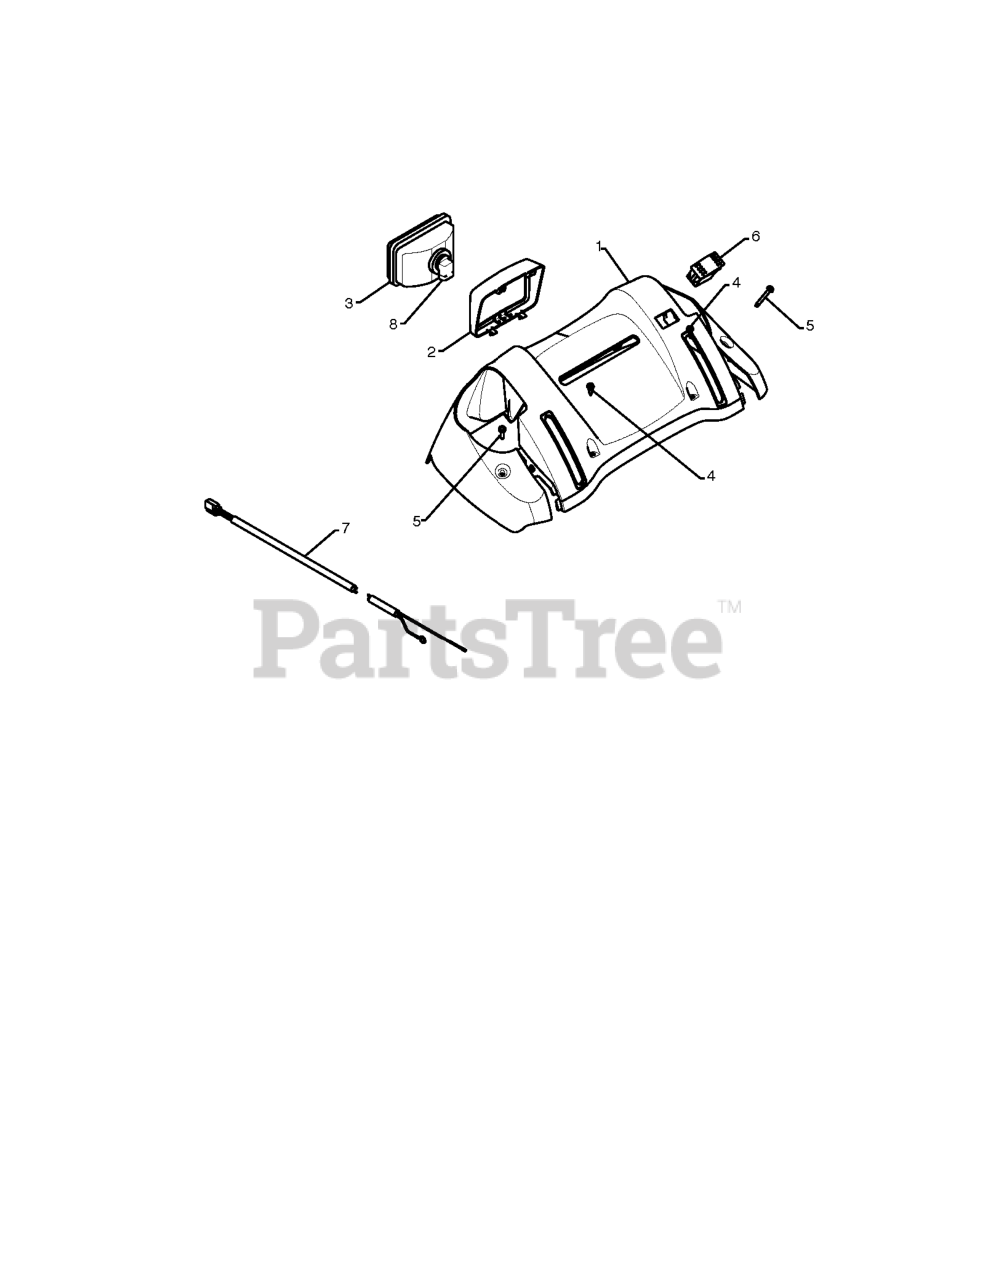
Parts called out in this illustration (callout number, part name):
1	PANEL.CONSOLE.
2	BEZEL.HEADLIGHT
3	HEADLIGHT.HALOGEN.SNOW
4	SCREW, HEX HEAD, TAPPING
5	SCREW, HEX HD TAPPING #10-24 1
6	SWITCH.HEATED.GRIP
7	HARNESS.WIRE.LIGHT/GRIP.SNOW
8	BULB.HEADLIGHT.HALOGEN.
